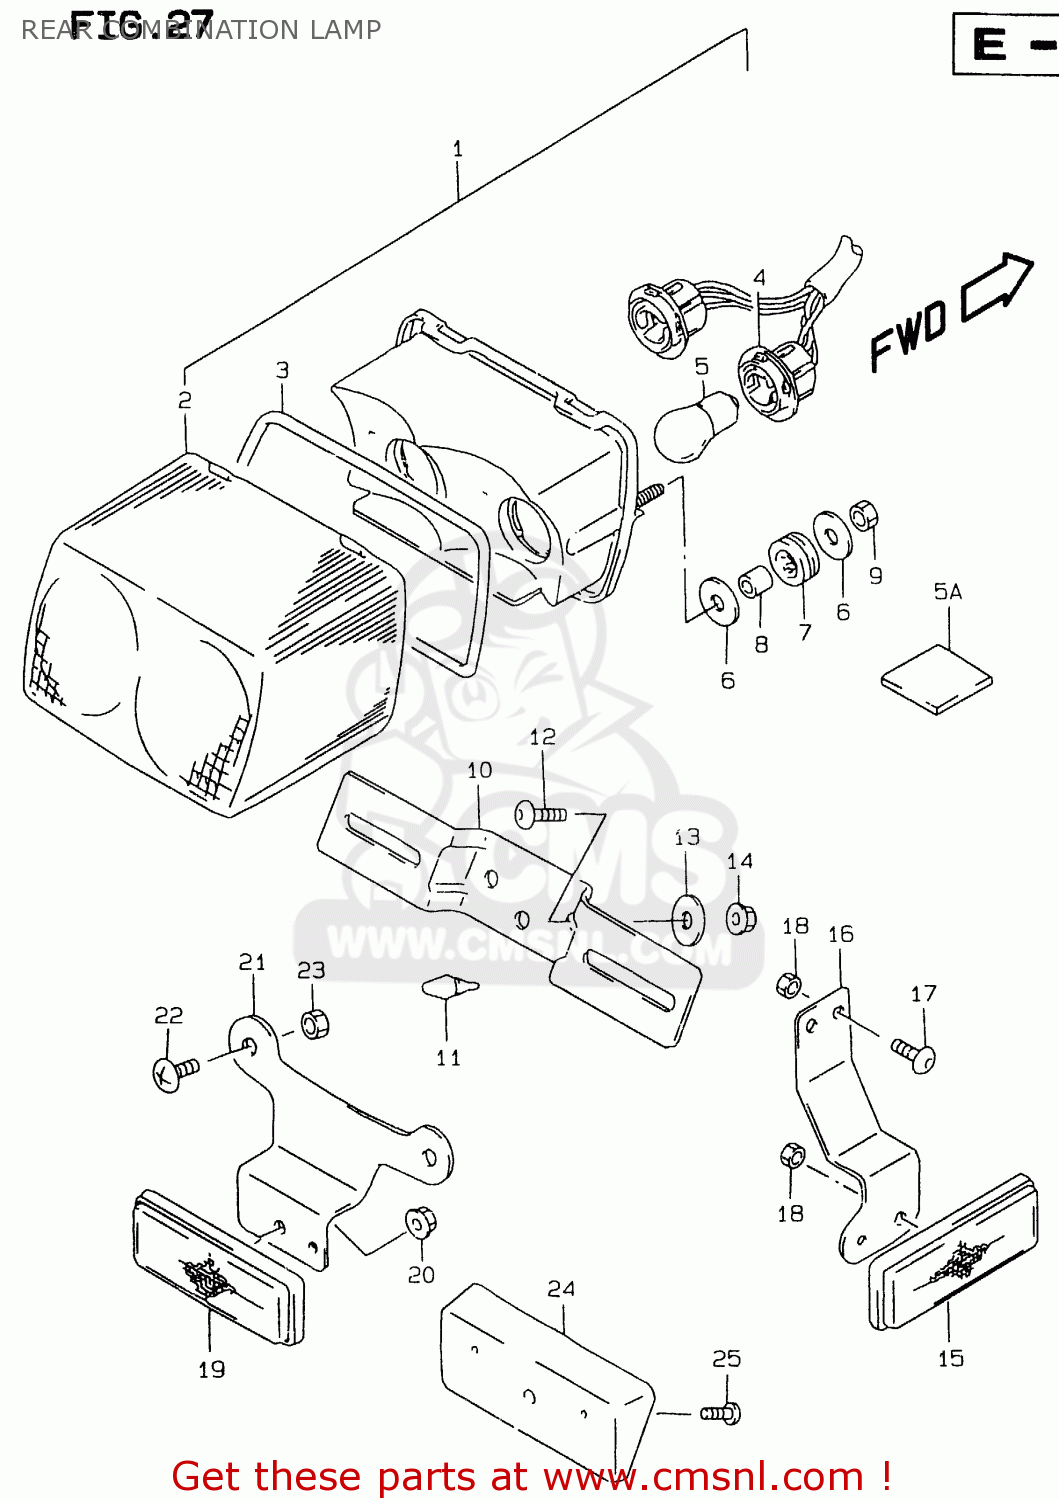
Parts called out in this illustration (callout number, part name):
1	LAMP ASSY,RR COMBINATION
2	LENS
3	GASKET (NAS)
4	SOCKET
5	BULB(12V21/5W)
5A	CUSHION,REAR LENS
6	WASHER(6.5X20X1.2)
7	CUSHION
8	SPACER(6.5X9X8.5)
9	NUT 6MM
10	BRACKET,LICENSE PLATE
11	CUSHION
12	SCREW
13	WASHER(6.5X20X1.2)
14	NUT 6MM
15	REFLEX REFLECTOR,FR SIDE
16	BRACKET,RR SIDE REFLECTOR
17	SCREW 5X12
18	NUT
19	REFLECTOR ASSY,RR
20	NUT
21	BRACKET,RR RR
22	SCREW 6X12
23	NUT 6MM
24	SPACER,RR RR
25	SCREW
